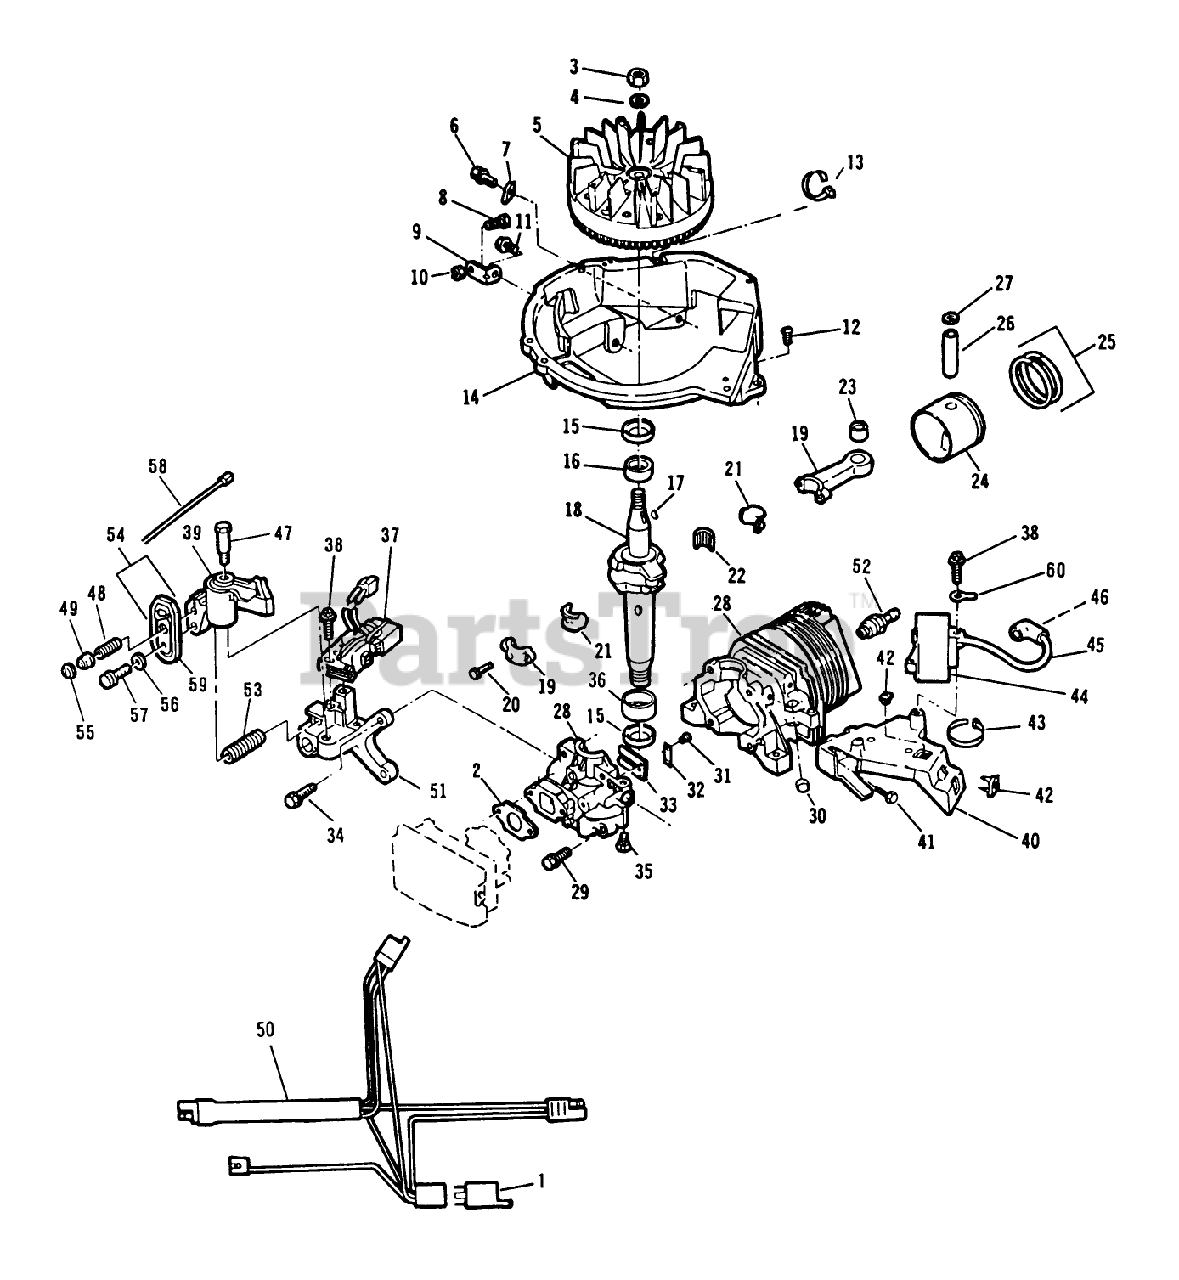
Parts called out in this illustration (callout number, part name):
2	GASKET CARB S
3	NUT
5	FLYWHEEL ASSY F
6	SCREW-SEMS
8	BOLT F
10	NUT-LOCK F
12	SCREW F
14	BASE SHROUD F
15	SEAL-OIL
16	BEARING V
17	KEY
20	SCREW-HSH
21	LINER ASM
22	BEARING-NEEDLE
23	BEARING AY F
27	RING-RETAINING
29	SCREW-H.W.HD. F
30	PLUG-CORE VF
31	SCREW-HH
32	PLATE-BACKUP, REED
34	SCREW
36	BEARING V
37	ALTERNATOR AY F
40	C.D. BRKT F
42	NUT-CLIP
45	HT LEAD&COVER XEV
48	SPRING
49	ACTUATOR-LEVER, BRAKE
51	BRACKET F
51	BRACKET-BRAKE F
53	SPRING-BRAKE
55	RETAINER S
56	WASHER
57	SCREW-SEMS
58	WIRE LEAD AY F
